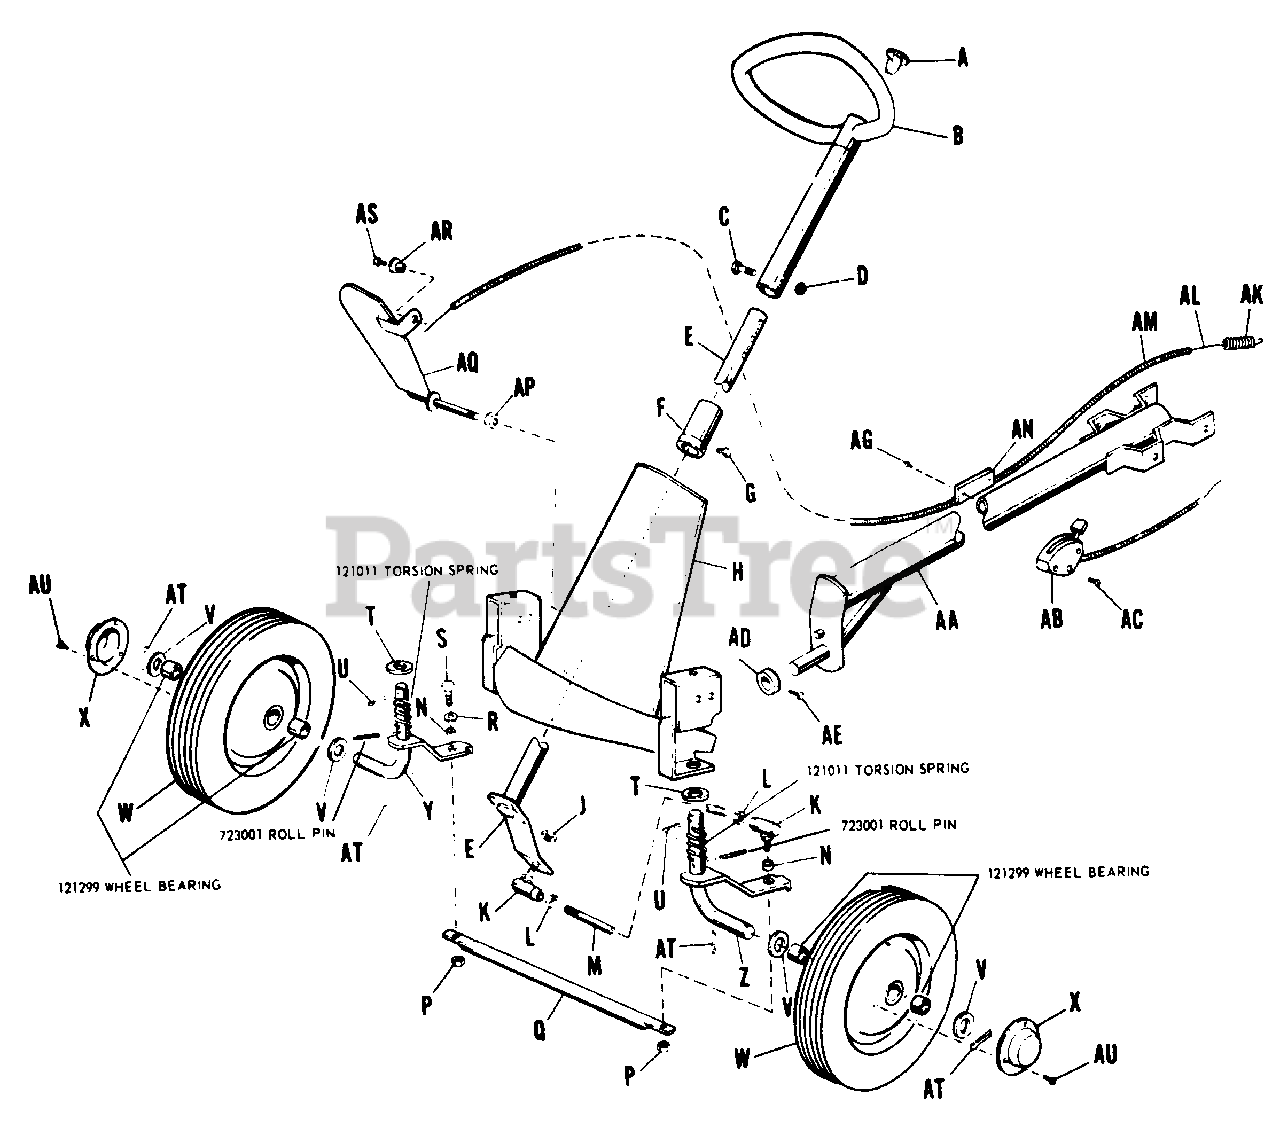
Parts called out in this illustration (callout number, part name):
A	Button, Plug
B	Handle, Steering
C	Capscrew, Hex Hd., 5/16 x 1 1/2
D	Nut, Hex, Full, 5/16-18 NC
E	Arm Assembly, Steering
F	Collar & Tube Assembly
G	Set Screw, S. Hd., Cup Pt. 5/16 x 1/2
H	Support, Steer Rod, Sub Assembly
J	Nut, Lock, Full Hex, 3/8-24
K	Ball Joint
L	Nut, Hex Full, 3/8-24
P	Nut, Lock Full Hex, 3/8-16
Q	Link Drag
R	Washer, Plain, 3/8
S	Capscrew, Hex Hd., 3/8 x 1
U	Cotter Pin
W	Wheel & Tire Assembly
X	Hub Cap, Front
Y	Spindle Assembly, R.H.
Z	Spindle Assembly, L.H.
AA	Frame Assembly, Front
AB	Throttle Control Assembly
AC	Screw, Self Tapping, #10-24 x 1/2
AD	Collar, Set
AE	Set Screw, Socket Hd., 5/16 x 3/8
AG	Screw, Self Tapping, #10-24 x 1/2
AL	Clutch Wire
AM	Clutch Wire Cable
AN	Cable Clamp
AP	Lock Nut, Full Hex, 3/8-16
AQ	Foot Pedal Assembly
AR	Clutch Wire Pivot
AS	Set Screw, Sq Hd., 1/4-20 x 3/8
AT	Cotter Pin
AU	Self-tapping Screw
